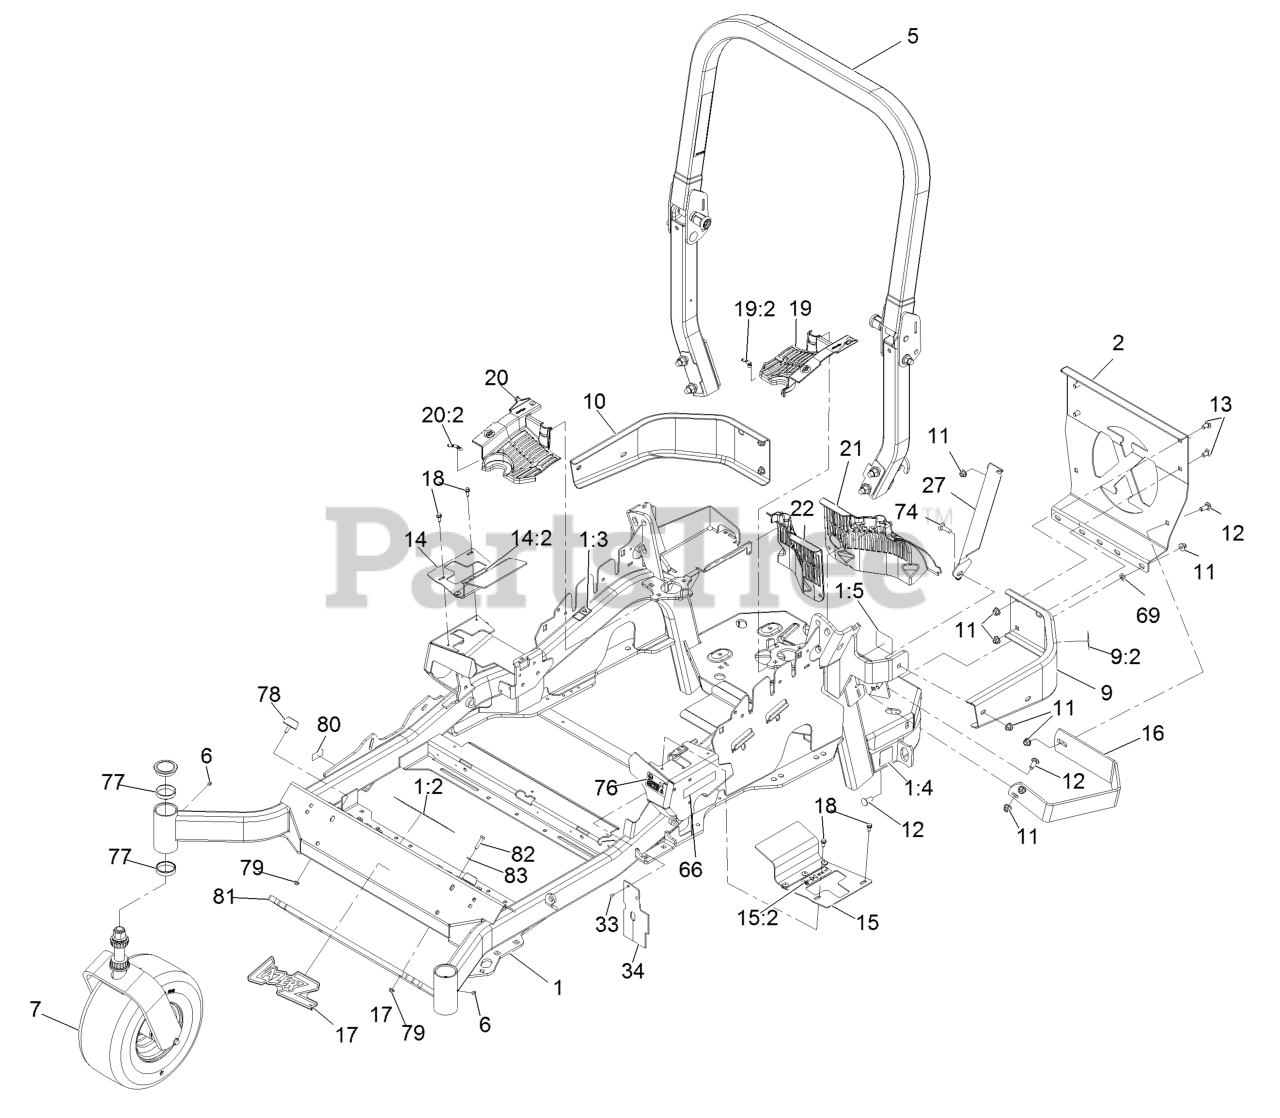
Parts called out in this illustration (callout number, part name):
1	MAINFRAME ASM
1:2	DECAL-WARNING, SLOPE
1:3	DECAL-WARNING
1:4	DECAL-HAZARD, PINCHED FINGER
1:5	DECAL-SPARK ARRESTER
2	PLATE,REAR GUARD
5	ROPS ASM
7	Front Caster W/Fork ASM
9	LH BUMPER ASM
9:2	DECAL-WARNING
10	BUMPER-RH
11	NUT-HF, NI
12	SCREW-CARR
13	SCREW-CARR
14	RH MOTION CONTROL COVER A
14:2	DECAL-CONTROL, MOTION
15	LH MOTION CONTROL COVER A
15:2	DECAL-CONTROL, MOTION
16	GUARD-MUFFLER
17	DECAL,LAZER MODEL
18	SCREW-HWH
19	LH HYDRO GUARD ASM
19:2	DECAL-OIL, HYDRO
20	RH HYDRO GUARD ASM
20:2	DECAL-OIL, HYDRO
21	GUARD-HYDRO, REAR (LH)
22	GUARD-HYDRO, REAR (RH)
33	RIVET-POP
34	DEFLECTOR-AIR FLOW
66	DECAL-E-SERIES
69	NUT-PUSH
74	BOLT-CARR
76	DECAL-FUEL FILL, CE
77	CUP-BEARING
80	Decal-Patent Ttco.Com
81	WEIGHT-TOE BOARD
82	SCREW-HH
83	WASHER-FLAT
